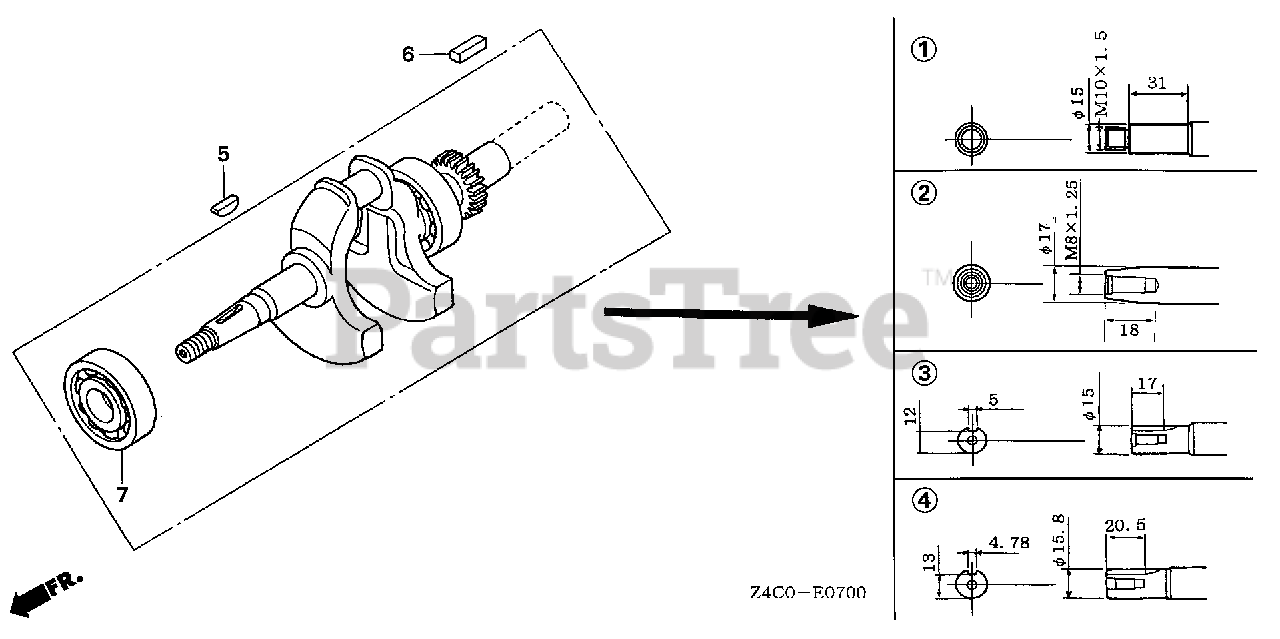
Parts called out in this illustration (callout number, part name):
1	CRANKSHAFT
5	KEY, SPECIAL
7	BEARING, RADIAL BALL (6203)
